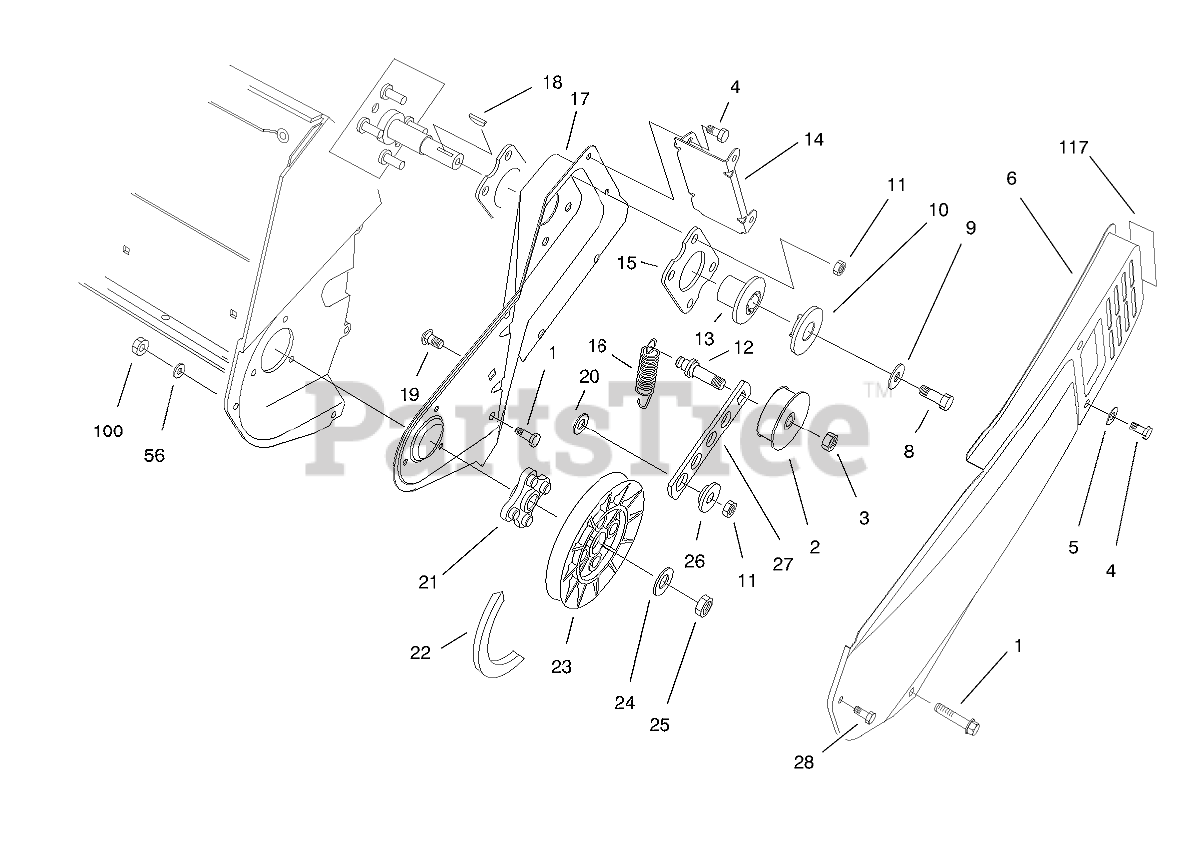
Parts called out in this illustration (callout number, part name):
1	SCREW-PLASTIC
2	PULLEY-IDLER
3	NUT-LOCK, NI
4	SCREW-HWH
5	WASHER-FLAT
6	Cover-Belt
8	SCREW-HH
9	WASHER-FLAT
10	CAP-HALF SHEAVE
11	NUT-LOCK, NI
12	PIN-IDLER
13	Hub-HALF SHEAVE
14	Bracket-Cover
15	Plate Engine
16	SPRING-EXTENSION
17	Sideplate-LH
18	KEY-WOODRUFF
19	SCREW-CARR
20	WASHER
22	V-BELT
23	PULLEY-DRIVEN
24	WASHER-FLAT
25	NUT-LOCK, NI
26	BUSHING-IDLER
27	ARM-IDLER
56	WASHER-FLAT
100	NUT-LOCK, NI
117	DECAL-HOT
